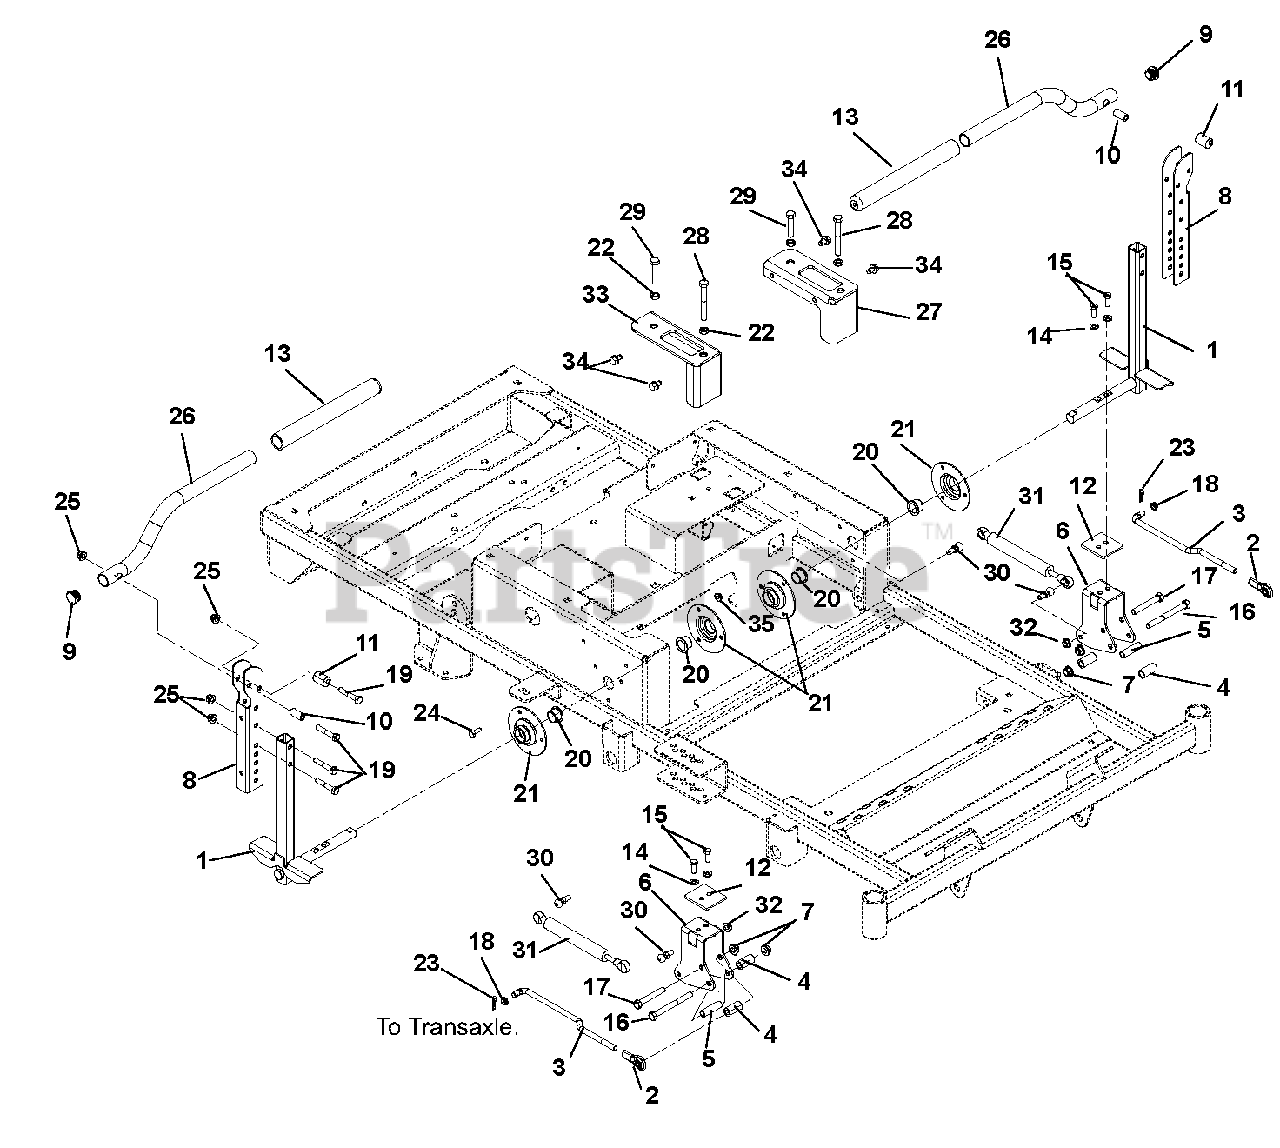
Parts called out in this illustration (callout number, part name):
1	Weldment, Control Link
2	Rod End, .38 Right Hand
3	Link, Transmission
4	Bushing, Spacer .390 x .625 x 1.25 Promaster
5	Spacer, Steering
6	Bracket, Steering
7	Nut, .38-16 Nyloc Flange
8	Channel, Upper Handlebar
9	Caplug, Handlebar
11	Eccentric
12	Plate, Steering Reinforcing
13	Grip, Handlebar
14	Washer, Locking .31 x .078
15	Bolt, Hex .31-18 x 1.00 Grade 8
16	Bolt-Hex .38-16X3.75 Grade 5
17	Bolt, Hex .38-16 x 2.50 Grade 5
18	Bushing, Polyliner 322-C
19	Bolt, Hex .31-18 x 1.75 Grade 5
20	Bushing, Flange .750 x 1.000 x .625 x 1.250
21	Bearing Flange
22	Nut, Hex Jam .375-16
23	Pin, Hair Internal .08 x .18 x 1.18
24	Bolt, Hex .25-20 x .75 Grade 5
25	Nut, .31-18 Nyloc Flange
26	Handlebar, ZTXL
27	Bracket, Left Hand Speed Control
28	Bolt, Hex .38-16 x 3.00 Grade 5
29	Bolt, Hex .375-16 x 1.750 Full Thread
30	Stud, Ball
31	Damper, ZT XL
32	Nut, Locking Top Flange .31-18
33	Bracket, Right Hand Speed Control
34	Screw, Tapping .31-18 x .50 Hex Washer Head
35	Nut, Locking-Top-Flange .25-20
